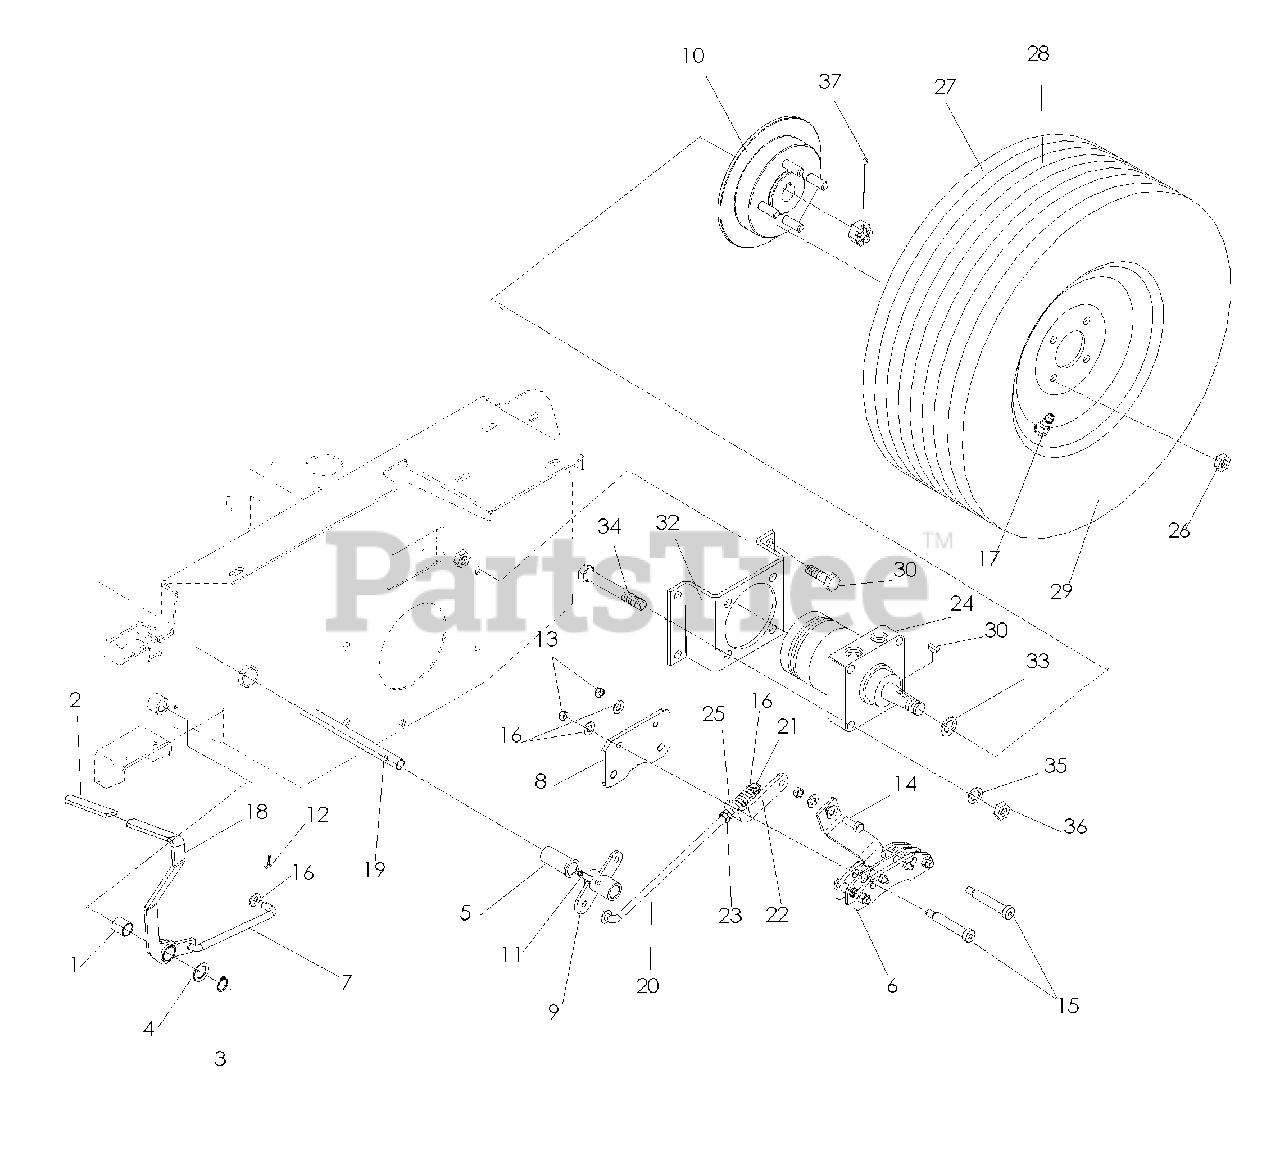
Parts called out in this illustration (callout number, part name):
3	RING, RETAINING 7/8
4	BUSHING, MACHINE
5	BUSHING, POLYMER 3/4 x 2
7	LINKAGE, BRAKE
8	PLATE, BRAKE
9	BELLCRANK, BRAKE
11	PIN, ROLL, 5/16" DIA
12	PIN, COTTER 3/32 x 3/4
13	NUT 3/8-16 JAM NYLOC
14	HCS 3/8-16 x 1
15	SB 3/8-16 x 2 1/2 SKT HD
16	WASHER 3/8 SAE FLT
17	VALVE STEM
18	BRAKE LEVER
19	SHAFT, CROSS
20	LINKAGE, REAR BRAKE
21	NUT 3/8-24 CENTERLOCK
22	BRACKET, L
23	NUT 3/8-24 JAM
24	WHEEL MOTOR, TJ
26	NUT 1/2-20 HEX LUG
27	TIRE, COMPLETE
28	TIRE, 23 x 95-12
29	RIM, OFFSET 1"
30	KEY, WOODRUFF
31	NUT 1/2-13 HEX NYLOC
32	STANDOFF, WHEEL MOTOR
33	BUSHING, MACHINE, 1"
34	HCS 1/2-13 x 2 3/4
35	LOCKWASHER 1/2
36	NUT 1/2-13 HEX
37	PIN, COTTER
